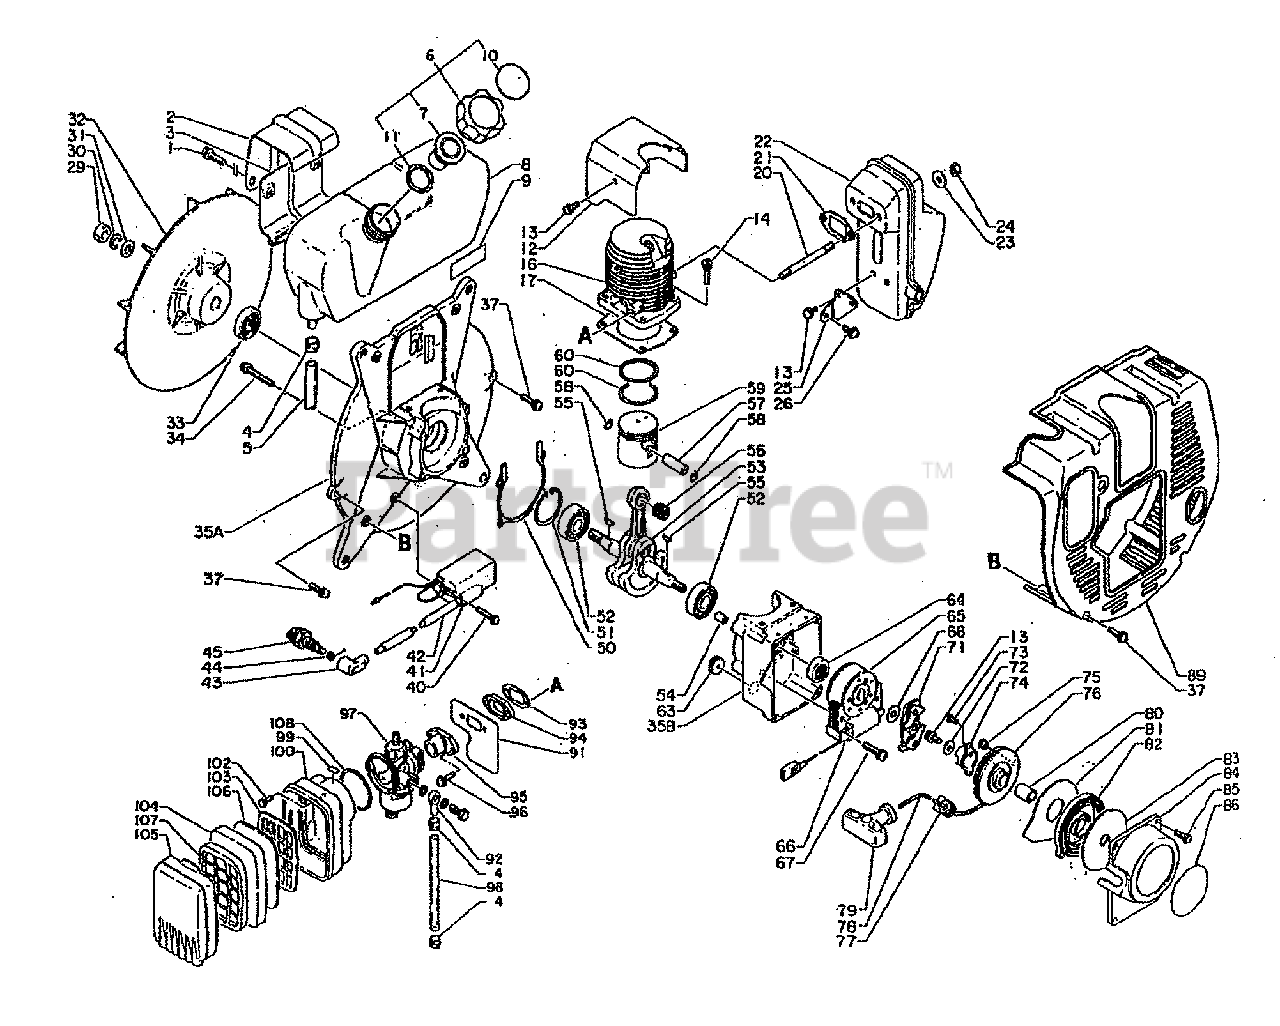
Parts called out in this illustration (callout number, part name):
1	BOLT 6×12
2	BRACKET, FUEL TANK
3	BRACKET, FUEL TANK
6	CAP ASSY, FUEL
7	CAP, VENT
8	TANK, FUEL
11	GASKET, FUEL CAP
12	COVER, CYLINDER
13	SCREW 5×10
14	BOLT 6×20
17	GASKET, CYLINDER
22	MUFFLER ASSY
24	NUT, LOCK
26	SCREW 5×14
31	WASHER 10.5×18×1.6
33	SEAL, OIL 18
34	BOLT 5×40
35	CRANKCASE SET
37	SCREW 5×20
40	SCREW 4×20
41	COIL, IGNITION
43	TERMINAL, SPARK PLUG
44	SPARK PLUG - BM6A
45	FLYWHEEL
50	GASKET, CRANKCASE
51	RING, SNAP 35
52	BEARING, BALL 6202
53	CRANKSHAFT ASSY
54	PIN, LOCATING
56	BEARING, NEEDLE
57	PIN, PISTON
58	RING, SNAP 8
60	RING, PISTON
64	SEAL, OIL
65	COIL, EXCITER
66	COIL, EXCITER
67	SCREW 5×25
71	PAWL ASSY, STARTER
72	WASHER 5.2×16×1.0
73	SCREW 4×8
74	PAWL CATCHER
75	CLIP, STARTER ROPE
76	REEL, ROPE
77	GUIDE, ROPE
78	ROPE, STARTER 3.5×850
81	PLATE, SIDE
82	SPRING, RECOIL
83	PLATE, SIDE
84	CASE, STARTER
85	SCREW 4×16
86	LABEL
89	COVER, ENGINE
91	GASKET, INTAKE
92	CONNECTOR
94	INSULATOR
95	ADAPTOR, INTAKE
97	CARBURETOR
99	LABEL
100	CASE, AIR FILTER
102	SCREW 4×14
103	GRID, AIR FILTER
104	PRE-FILTER, FOAM
105	COVER, AIR FILTER
106	FILTER, AIR
107	GRID, PRE-FILTER
